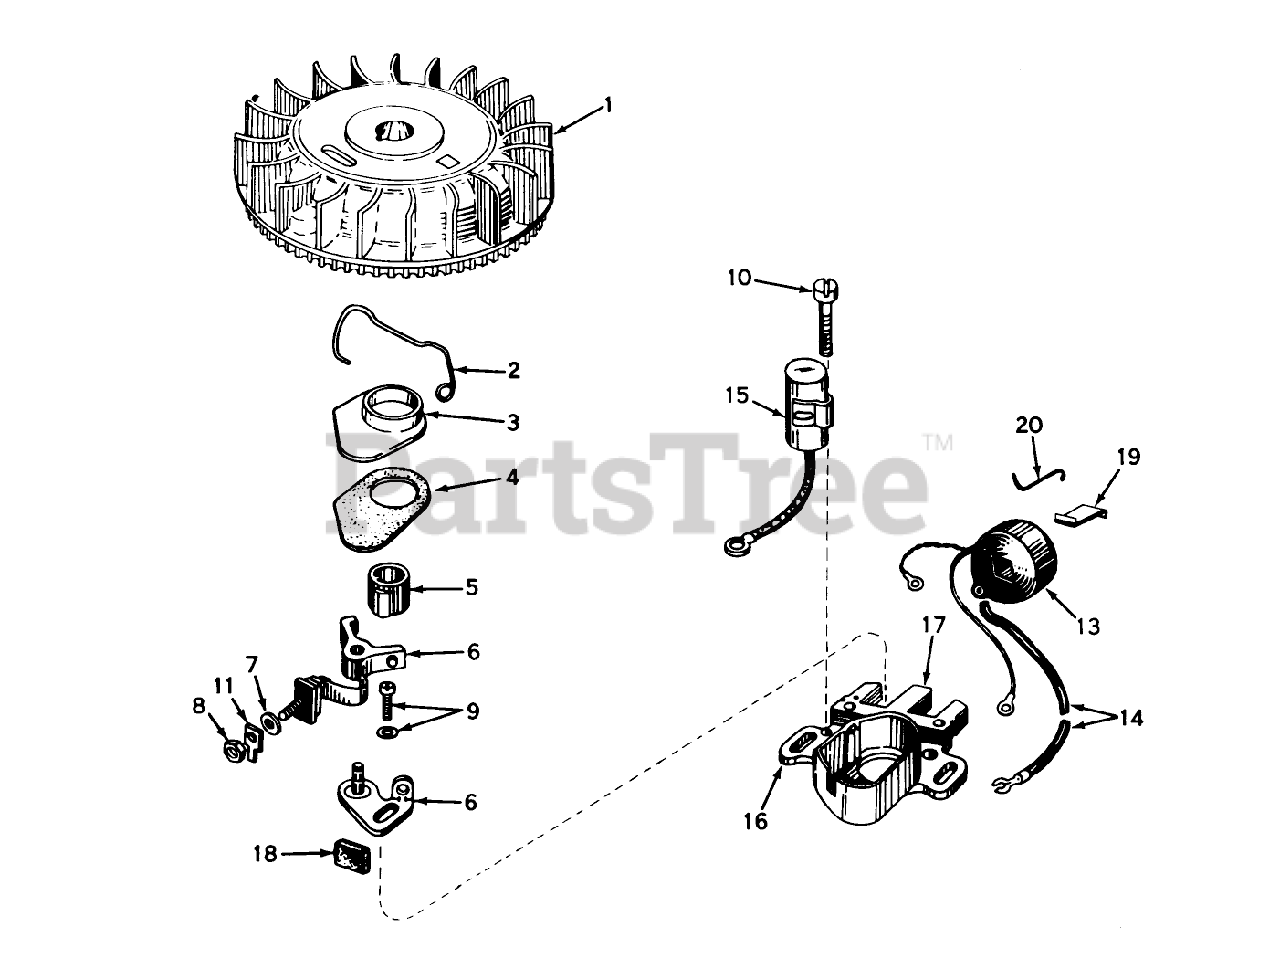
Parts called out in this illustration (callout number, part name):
1	Flywheel
2	Spring Breaker Box
3	Cover, Dust
4	Gasket Dust Cover
5	Cam-Breaker
6	Breaker Assy.
7	Washer
8	DECAL
9	Breaker Screw
10	Condenser Screw
11	Terminal
13	Coil Assy. (Incl. No. 12)
14	Wire, Lead
15	Condenser
16	Core Plate
17	Stator Assy., (Incl. Nos. 2, 3, 5 thru 14 16 thru 19)
18	Felt,Cam Wiper
19	Spring Coil Wedge
20	Clip, Coil
